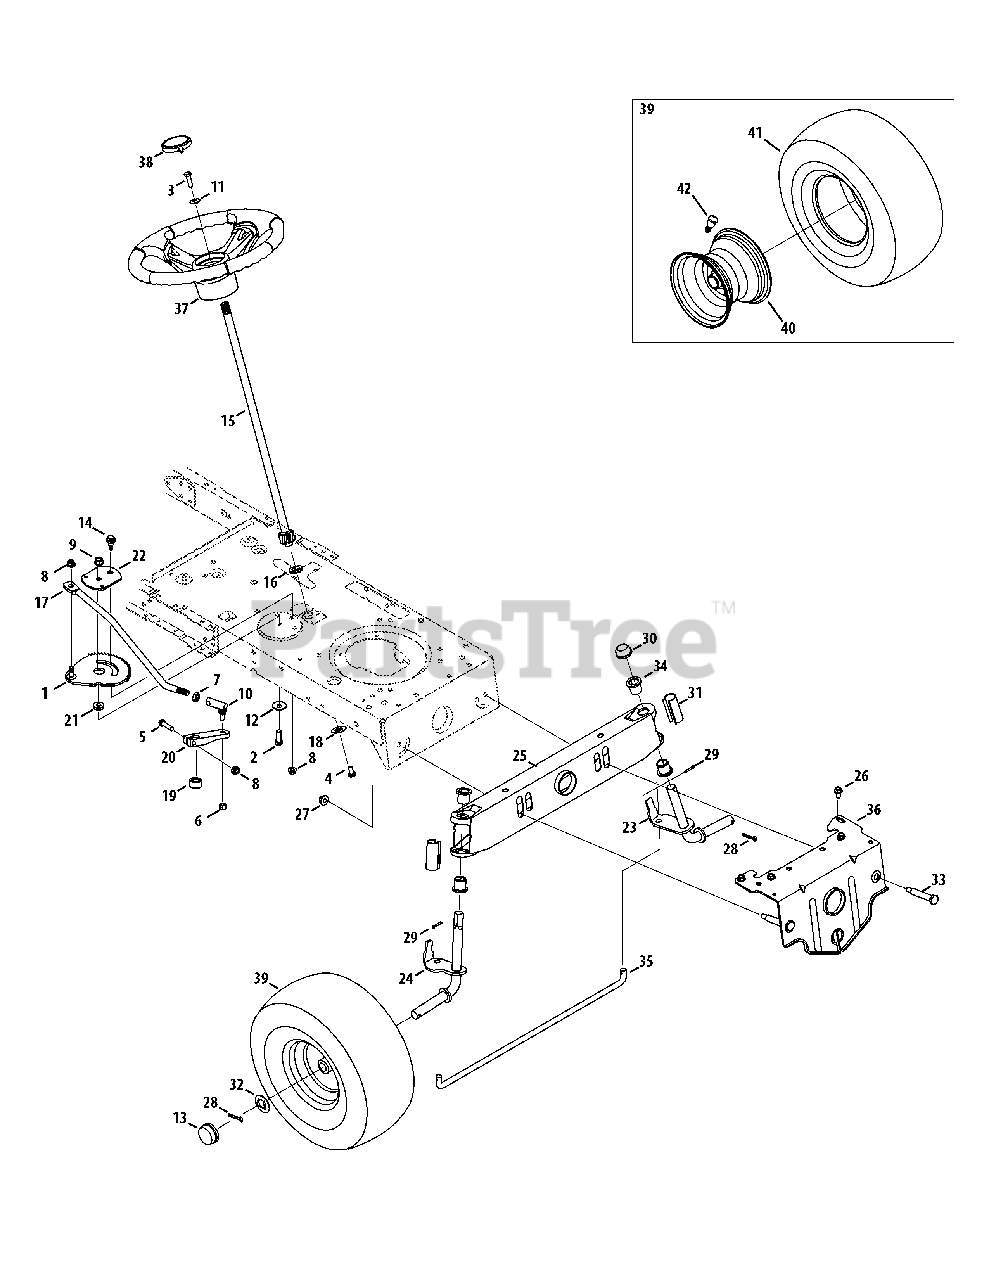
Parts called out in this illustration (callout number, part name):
1	Gear Assembly, Steering
2	Hex Head Screw, 3/8-16 x 1.00
3	Screw, 5/16-18, 1.00, Gr5, Lock
4	Screw, Mach, 5/16-18, 0.750
5	Screw, 5/16-18, 1.75, Gr5
6	Nut, Jam Lock, 3/8-24
7	Nut, Jam, 7/16-20, Gr2
8	Nut, Flange Lock, 5/16-18, Grf
9	Nut, Flange Lock, 3/8-16, Grf
10	Ball Joint, 7/16-20, Lock
11	Washer, Bell, .340 x .872 x .060
12	Bevel Washer, .390 x 1.130 x .062
13	Hub Cap
14	Shoulder Screw, 5/16-18
15	Steering Shaft, 5/8 Spline
16	Bearing, Flange, Hex 5/8
17	Drag Link, Steering
18	Cap, 1.25 x .16
19	Spacer, .710 ID x .125 OD x .56
20	Steering, Block
21	Spacer, .38 x .854 x .20
22	Stabilizer Gear Plate
23	Axle Assembly LH
24	Axle Assembly RH
25	Pivot Bar Axle Assembly
26	Screw, 5/16-18, 0.750
27	Nut, Flange Lock, 3/8-16, GrF
28	Pin, Cotter, 5/32, 1.25
29	Pin, Cotter, 1/8 x 0.75
30	Push Cap, 3/4
31	Axle Cap
32	Washer, Flat, .781 x 1.59
33	Screw, Shlder, .500 x 2.380, 3/8-16
34	Flange Bearing
35	Tie Rod
36	Pivot Bar Bracket
37	Steering Wheel, Standard Grip
38	Cap, Steering Wheel (Crafts. logo)
39	Wheel Assembly
41	Tire, 15 x 6 x 6 Rd. Shoulder
42	Valve Stem
